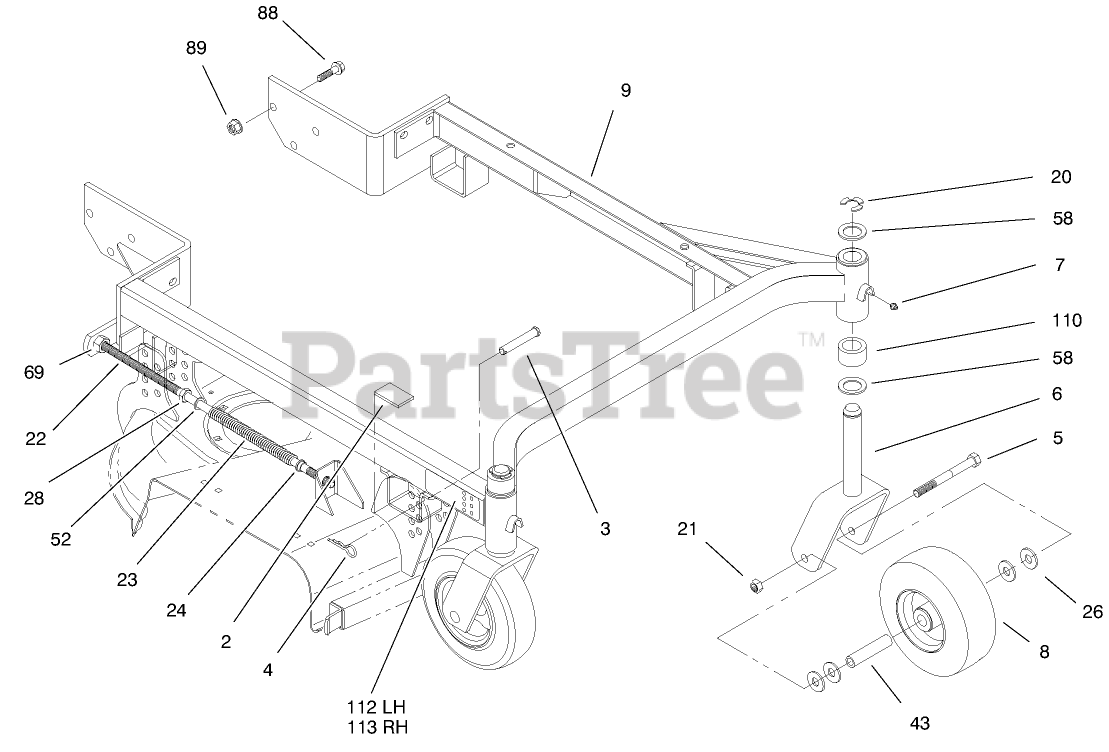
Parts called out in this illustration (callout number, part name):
2	CUSHION-RUBBER
3	PIN-CLEVIS
4	PIN-HAIR
5	SCREW-HH
6	Castor Fork
7	FITTING-GREASE
8	CASTOR WHEEL ASM
8:3	BEARING-OUTSIDE
8:4	BEARING-ROLLER
8:6	FITTING-LUBE, 45 DEG
9	WA - CARRIER FRAME 52"
20	RING-RETAINING
21	NUT-HEX
22	SHAFT-ADJUSTING
23	SPRING
24	BUSHING-FLANGE
26	WASHER-FLAT
28	NUT-JAM
43	SPANNER-TIRE
52	WASHER
58	WASHER-THRUST
69	NUT-LOCK, NI
110	SPACER-CASTOR
112	DECAL-HOC, LH
113	DECAL-HOC, RH
